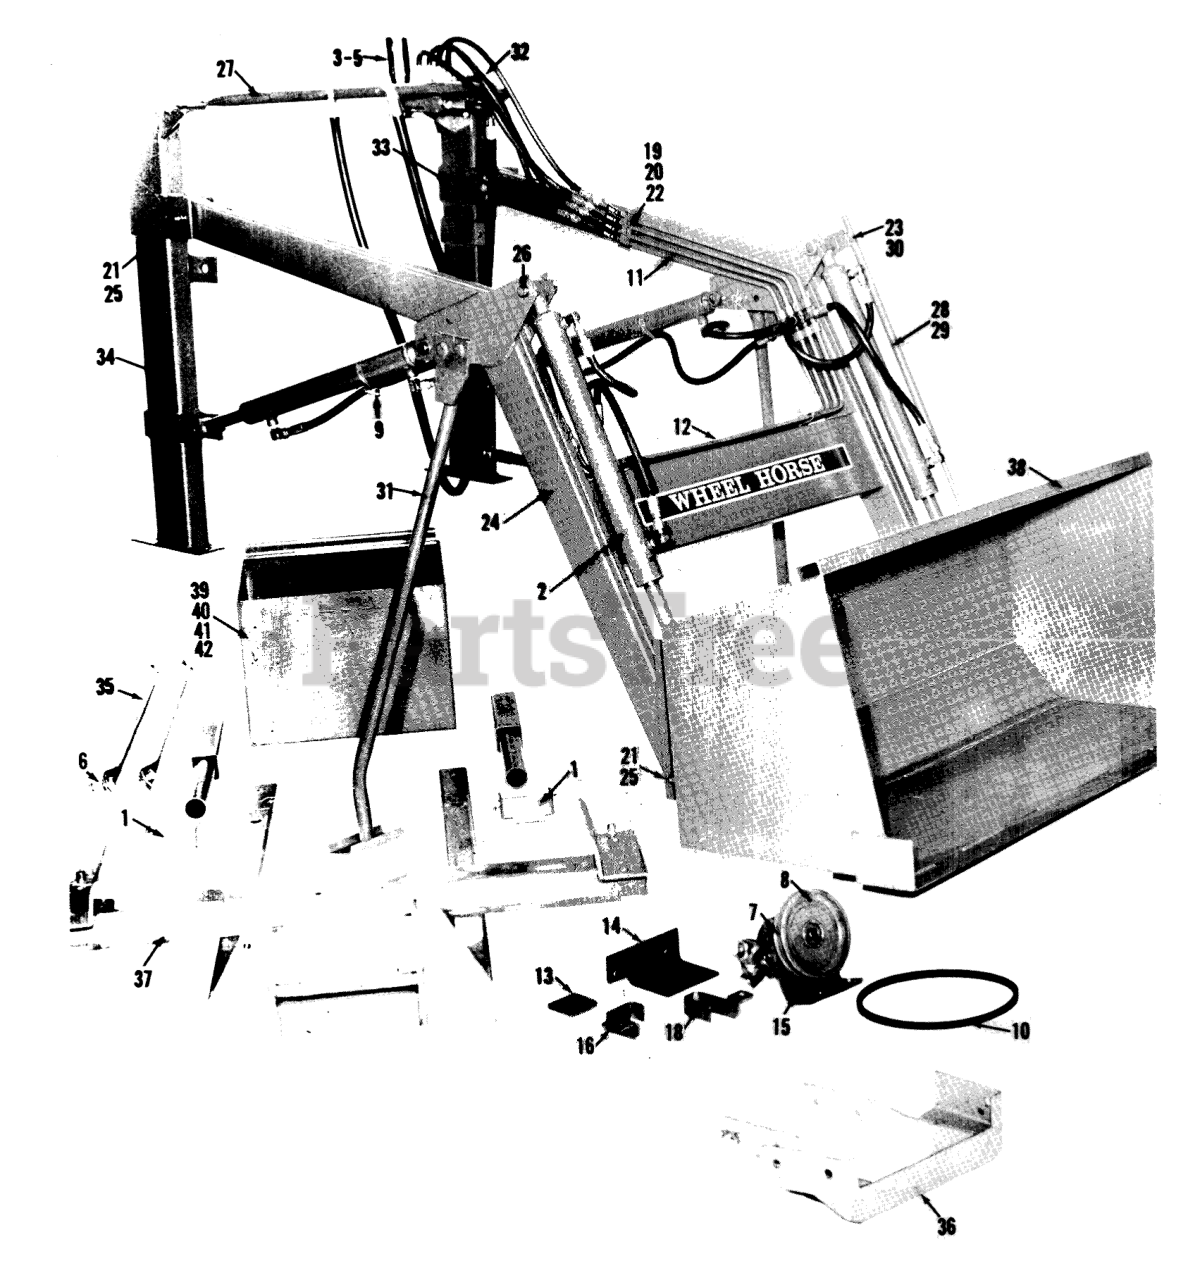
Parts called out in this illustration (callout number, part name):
1	Underframe Mounting Brackets
2	Tilt Cylinder
3	Control VaIve
4	Handle Linkage
5	Valve Handle
6	Brace Arm Spacer
7	Pump
8	Pulley
9	52014/15/90A RER 34
10	Gates V-Belt 2250
11	Hydraulic MetaI Line-Arm
12	Self Tapping Screw
13	Pump Support Plate Spacer
14	Pump Mounting Support Plate
15	Pump Mounting Bracket
16	Left Hose Bracket (Front Mounting)
18	Key-Timing
19	Hydraulic Line Hold Down
20	Hydraulic Line Bracket
21	Grease Fitting
22	Foam Cushion
23	Spacer/Bushing
24	Boom Assembly
25	Pivot Pins-Boom to Bucket & Boom to Uprights
26	Cylinder Attaching Pin
27	Cross Tie
28	Guide Tube
29	Guide Rod
30	Tapped Pivot Pin
31	Parking Stand (Left)
31	Parking Stand (Right)
32	Breather Cap
33	Upright Assembly (Left)
34	Upright Assembly (Right)
35	Brace Arm
36	Front Mounting Assembly
37	Underframe Assembly
38	Bucket Assembly
39	Ballast Box
40	Ballast Box Bracket
41	Ballast Box Hitch
42	Ballast Box Door
